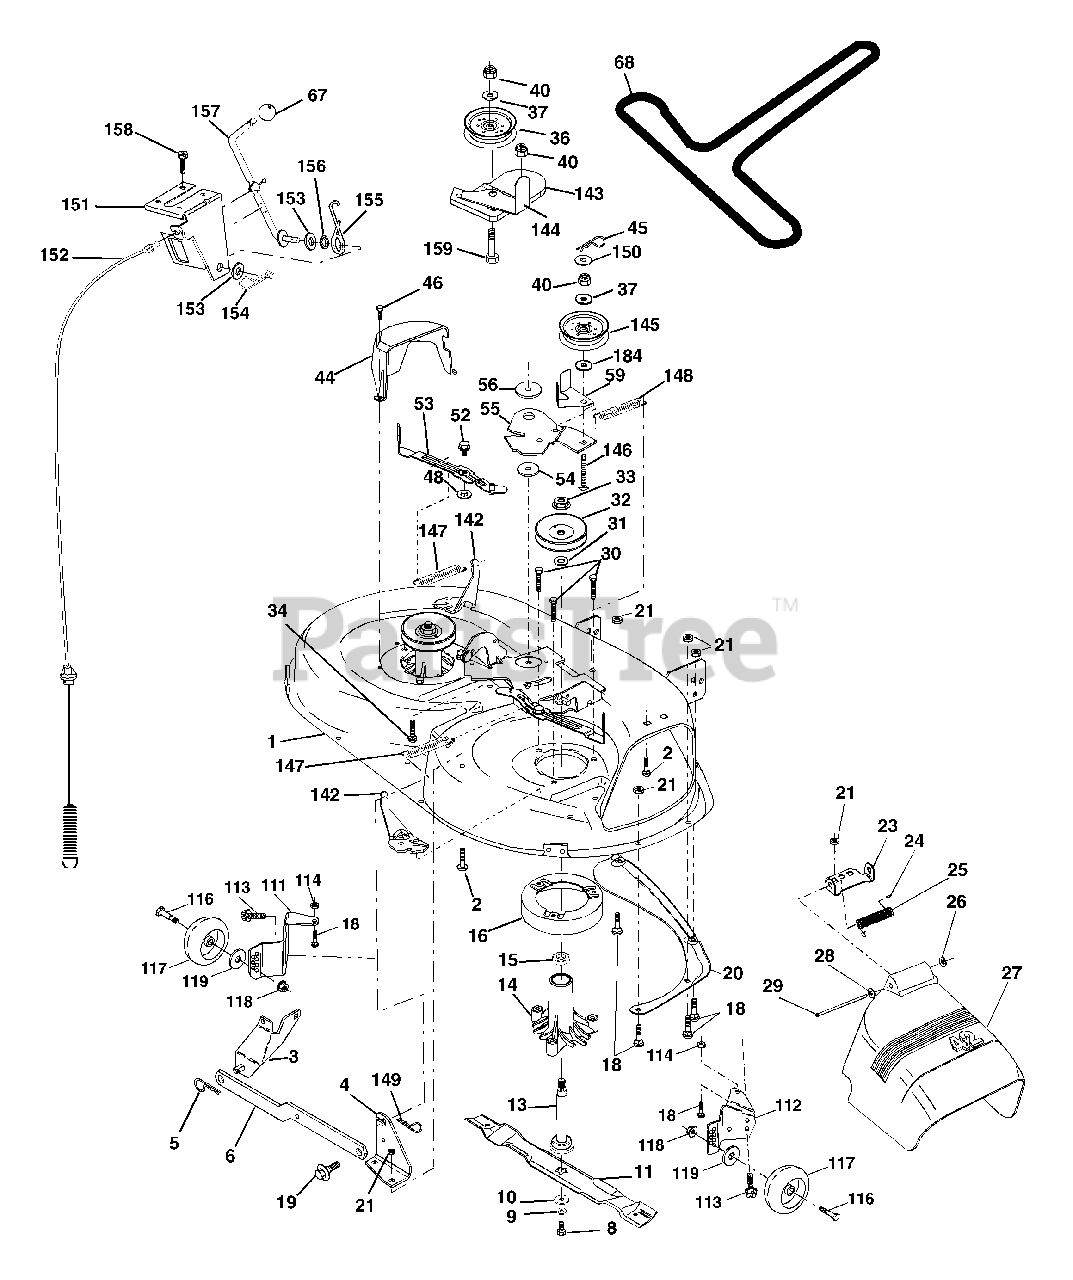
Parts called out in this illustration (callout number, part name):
1	Mower Deck Assembly, 42"
2	Bolt
3	Bracket Asm Fr. Sway Bar 3/42
4	Bracket Asm Deck 42" Sway Bar
5	Retainer Spring
6	Bar Sway Deck
8	Bolt 3/8-24 x 25 Grade 8 patched
9	Washer, Lock
10	Washer, Hardened
11	Blade, 42" Mulching Std
11	Blade, 42" Mulching Premium
11	Blade, 42" Hi-Lift
13	Shaft Assembly, Mandrel, Vented
14	Housing, Mandrel, Vented
15	Bearing, Ball, Mandrel
16	Stripper, Vented Mower Deck
18	Bolt, Carriage 5/16-18 x 5/8
19	Bolt, Shoulder
20	Baffle, Vortex
21	Nut
23	Bracket, Deflector Mower 42"
24	Cap, Sleeve 80 x 112 Blk Mower
25	Spring, Torsion, Deflector 2 52
26	Nut, Push Phos & Oil
27	Shield, Deflector 42" Blk
28	Washer 11/32 x 5/8 x 16 Gauge
29	Rod, Hinge 42" 6 75 W/G
30	Screw Thdrol Washer Head
31	Washer, Spacer Mower Vented
32	Pulley, Mandrel
33	Nut, Toplock Flange
34	Bolt
36	Pulley, Idler, Flat
37	Washer 13/32 x 13/16 x 16 Gauge
40	Nut
44	Guard, Mandrel, LH
45	Retainer
46	Screw, Thdrol 1/4-20 x 5/8 T
48	Washer, Hardened
52	Bolt, Shoulder 5/16-18 UNC
53	Arm Assembly, Pad, Brake
54	Washer, Hardened
55	Arm, Idler
56	Spacer, Retainer
59	Guard TUV Idler
67	Knob
68	V-Belt, 42" Mower
111	Bracket Wheel Gauge Lh
112	Bracket Wheel Gauge RH
113	Screw 3/8-16 x .625
114	Nut Keps 5/16-18
116	Bolt Shld "A" 2.41 "B" 1.66
117	Wheel Gauge
118	Nut Centerlock 3/8-16 Unc
119	Washer 3/8 x 7/8 x 14 Ga.
142	Arm Spring Brake Mower
143	Bracket Arm Idler 42"
144	Keeper Belt 42" Clutch Cable
145	Pulley Idler Flat
146	Bolt Carriage Idler
147	Spring Extension
148	Spring Return Idler
149	Retainer Spring Yellow
150	Washer 9/32 x 3/4 x 16 Ga.
151	Bracket Clutch Cable
152	Clutch Cable 42"
153	Washer Flat 3/8" Type B
154	Spring Retainer
155	Spring Retention LVR CLTCH CAB
156	Spacer Clutch Cable
157	Rod Clutch Cable 3/8"
158	Screw Hex Thd Cut 1/4-20 x 1/2
159	Bolt Rdhd Sqn 3/8-16 UNC x 1-3/4
184	Washer 13/32 x 7/8 x 10 Ga.
